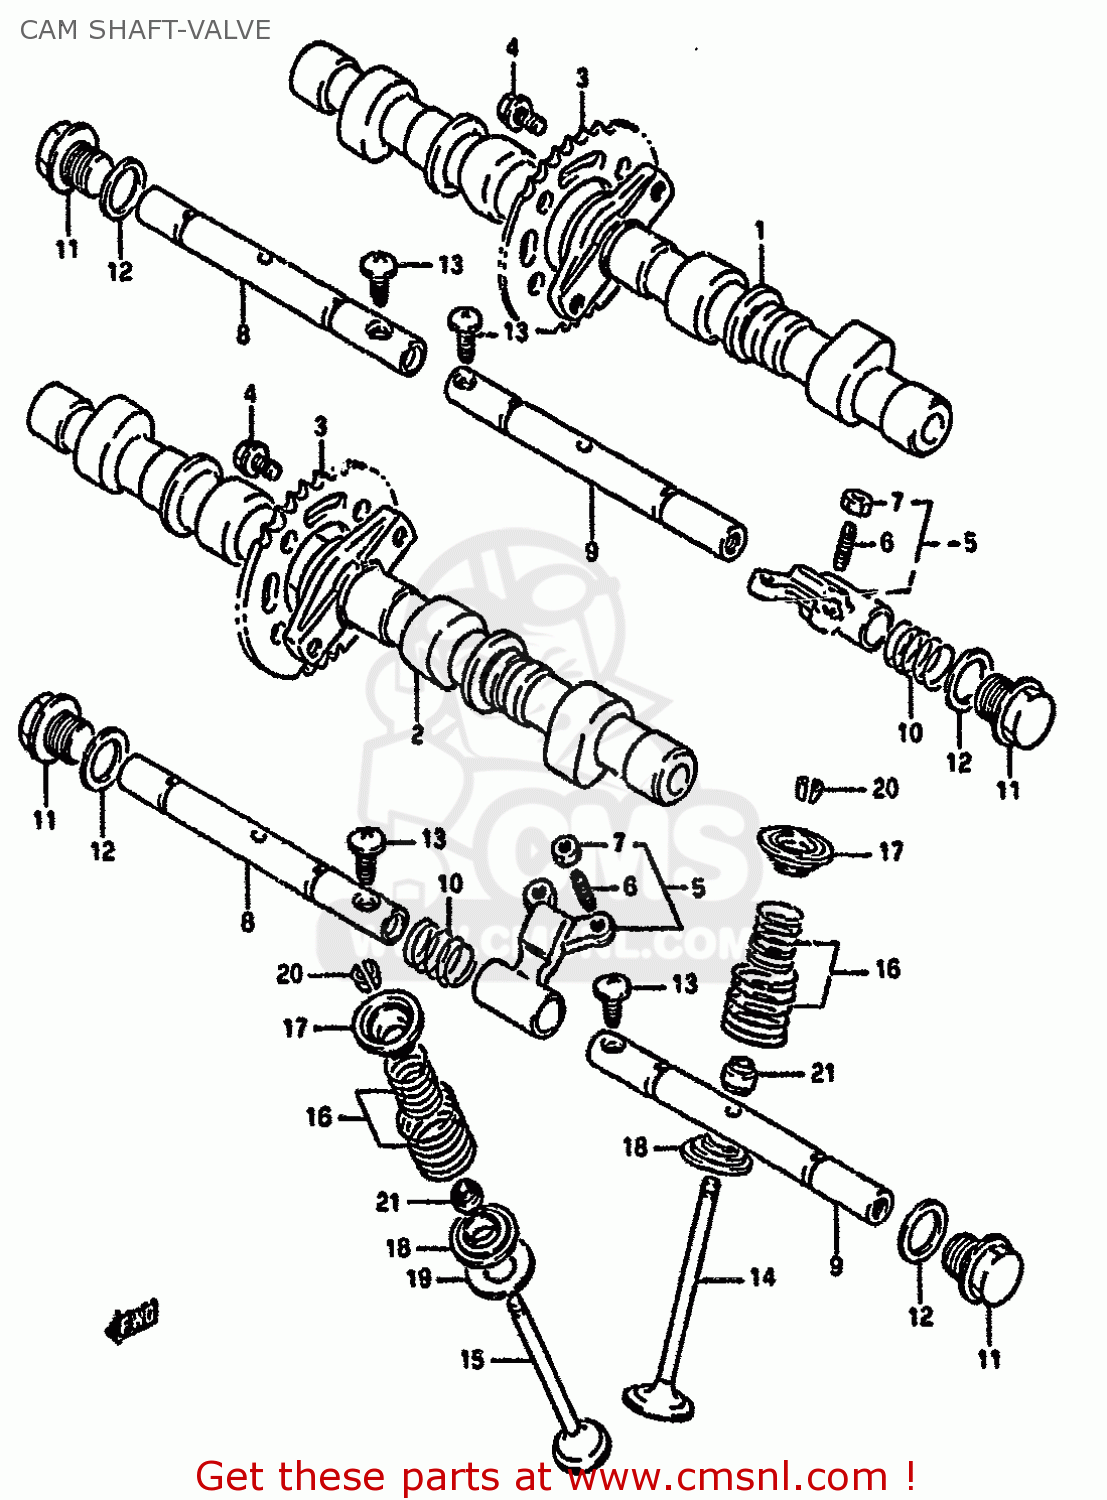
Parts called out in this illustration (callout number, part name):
1	CAMSHAFT
2	CAMSHAFT,EXHAUST
3	SPROCKET,CAMSHAFT
4	BOLT(7X10)
5	ARM,VALVE ROCKER
6	SCREW,TAPPET ADJUSTING
7	NUT,ADJUSTING
8	SHAFT,VALVE ROCKER ARM
9	SHAFT,VALVE ROCKER ARM
10	SPRING
11	PLUG
12	GASKET(14X19.2X2) (NAS)
13	SCREW(6X16)
14	VALVE,INTAKE
15	VALVE,EXHAUST
16	SPRING SET,VALVE
17	RETAINER,VALVE SPRING
18	SEAT,VALVE SPRING
19	SEAT,VALVE SPRING EXH OUTER
20	COTTER VALVE
21	SEAL,OIL(4.5X10X8)
